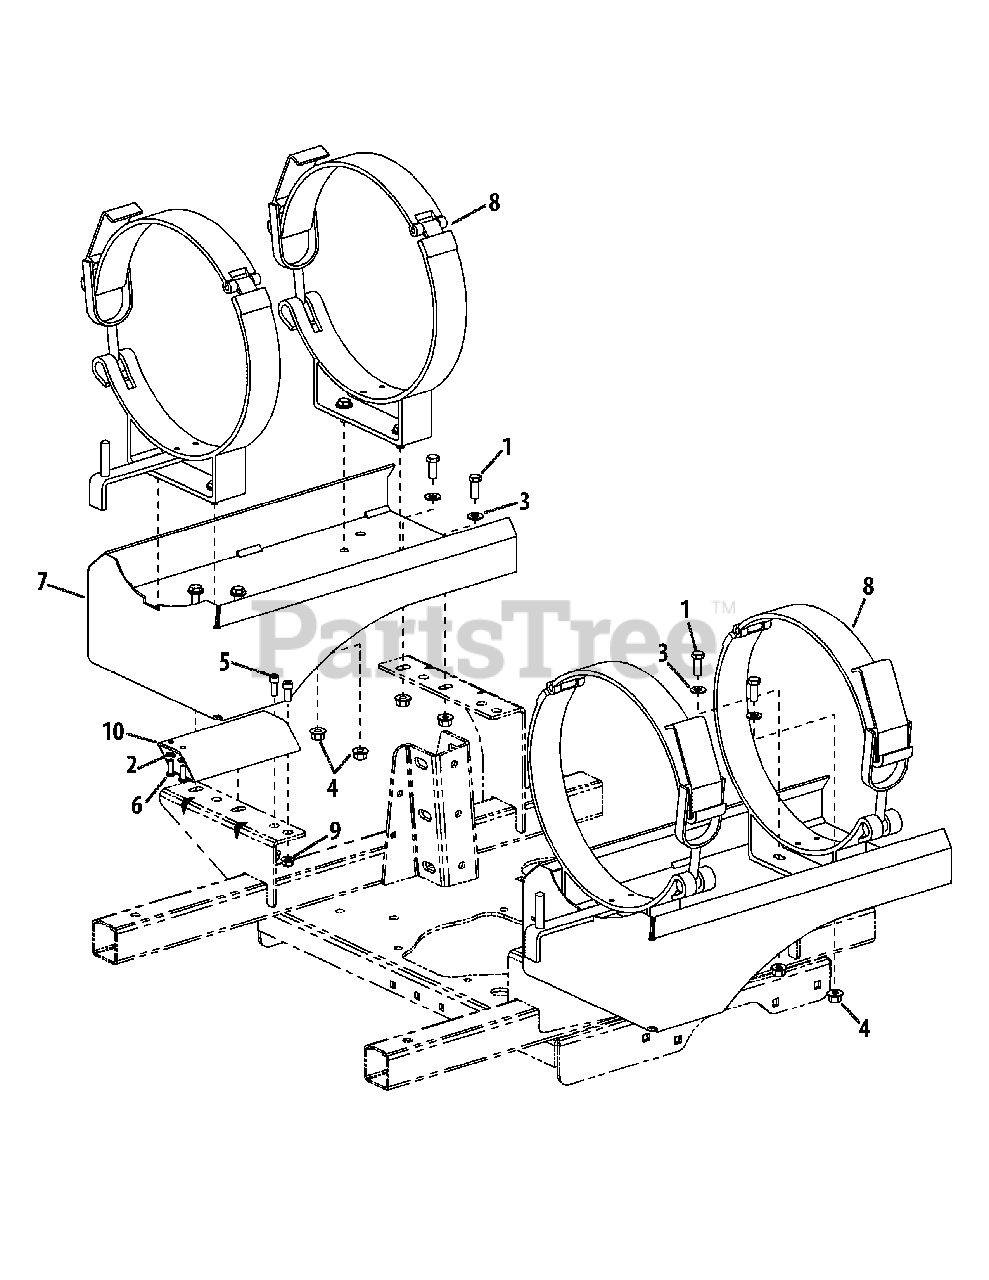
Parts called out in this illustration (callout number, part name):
1	Hex Screw, 3/8-16 x 1.00
2	Lock Washer, 1/4
3	Washer, .406 x .813 x .063
4	Flange Counter Lock Nut, 3/8-16
5	Socket Cap Screw, 5/16-18 x 3/4
6	Button Cap Screw, 1/4-20 x .750
7	LPG Tank Bracket Assembly
8	LPG Tank Mount Bracket Assembly
9	Flange Lock Nut, 5/16-18
10	Regulator Tube Bracket
